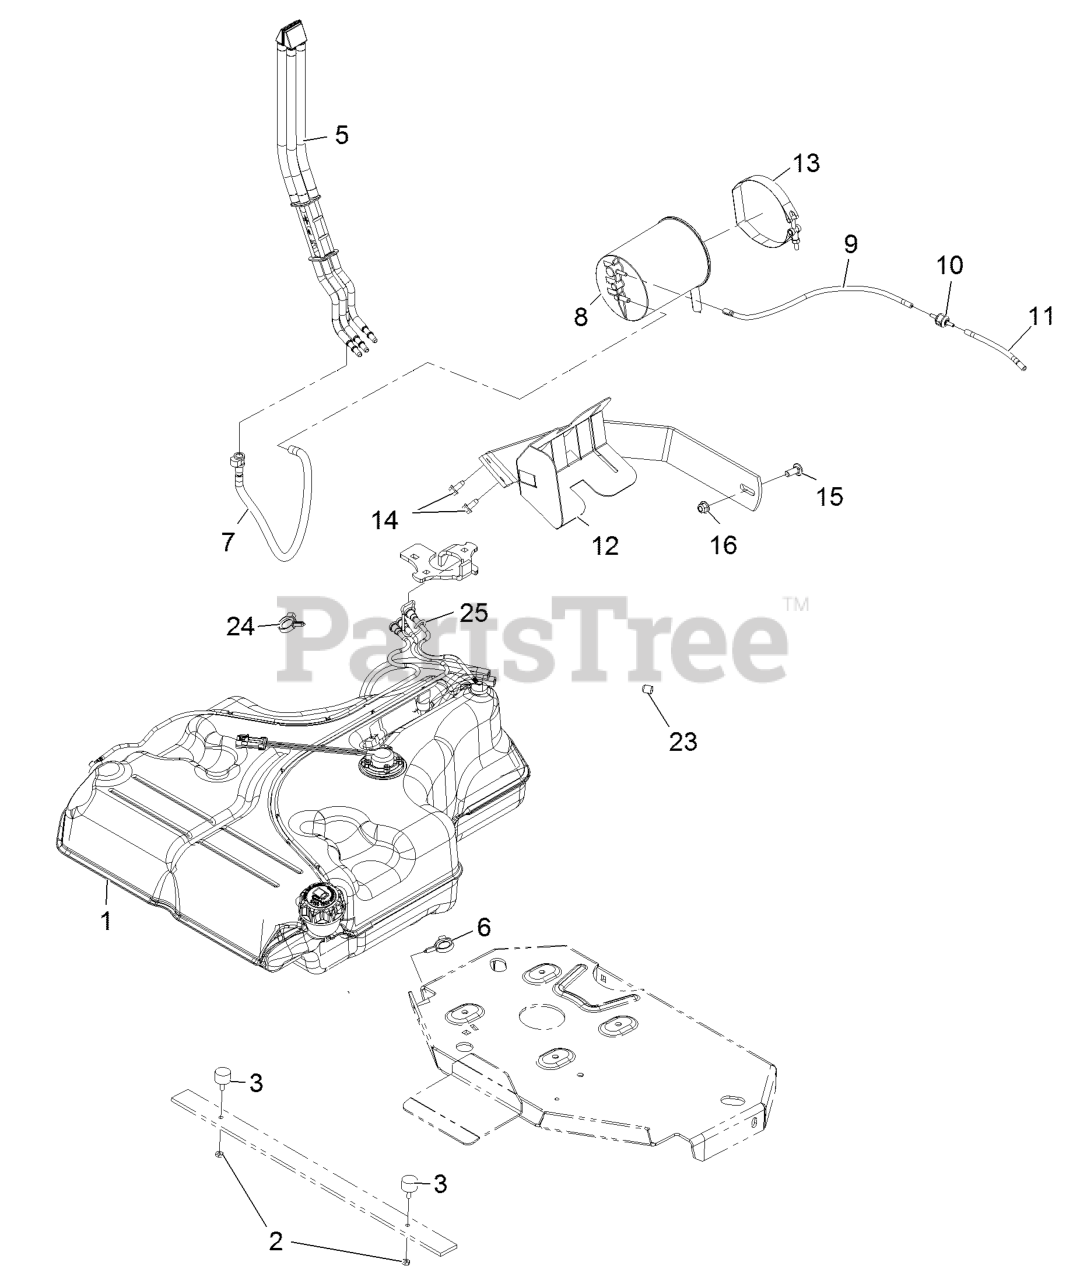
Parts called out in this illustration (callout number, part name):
2	NUT-JAM
5	FUEL MANIFOLD VENT ASM
6	CLAMP-HOSE
7	VENT HOSE ASM
8	CANISTER-CARBON, 1200CC
9	HOSE-VENT, FORMED
11	HOSE-VENT, FORMED
12	MOUNT-CANISTER
13	CLAMP, T-BOLT
14	Screw-HWH 5/16-18 X 3/4 Tf
15	SCREW-CARR
16	NUT-HF, NI
23	PLUG-PORT
24	CLAMP-HOSE
25	RETAINER-LINE, VAPOR
